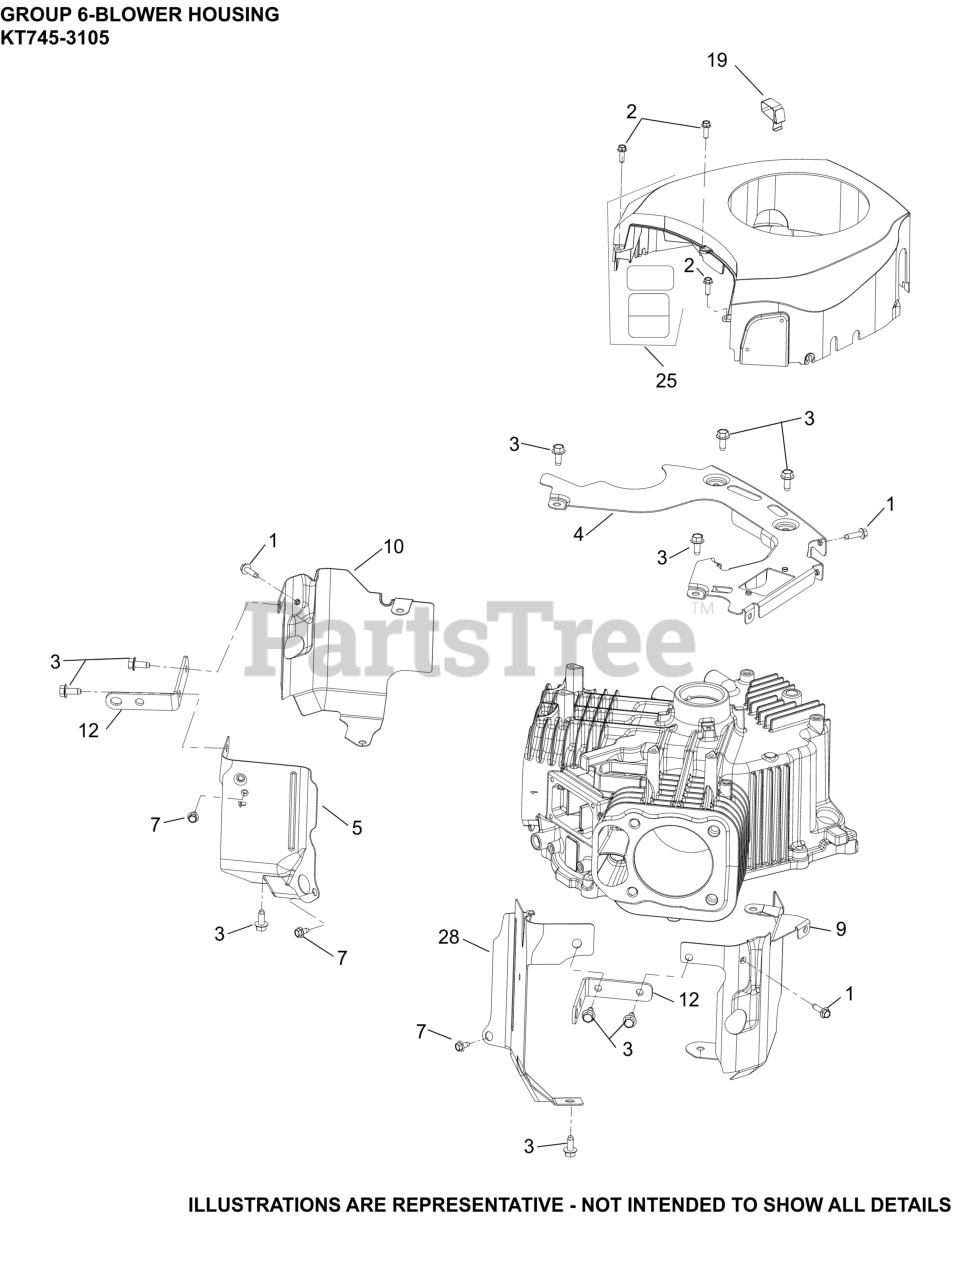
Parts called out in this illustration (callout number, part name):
1	SCREW, THD FRM-USE 25 086 473-S
2	SCREW, HI-LOW
3	SCREW, THREAD FORMING
4	PLATE, BACKING
5	BAFFLE, VALLEY #1
7	SCREW, THREAD FORMING
9	BAFFLE, LEFT BARREL
10	BAFFLE, RIGHT BARREL
12	STRAP, LIFTING
19	CLIP, BLOWER HOUSING
25	KIT, BLOWER HOUSING
28	BAFFLE, VALLEY #2
